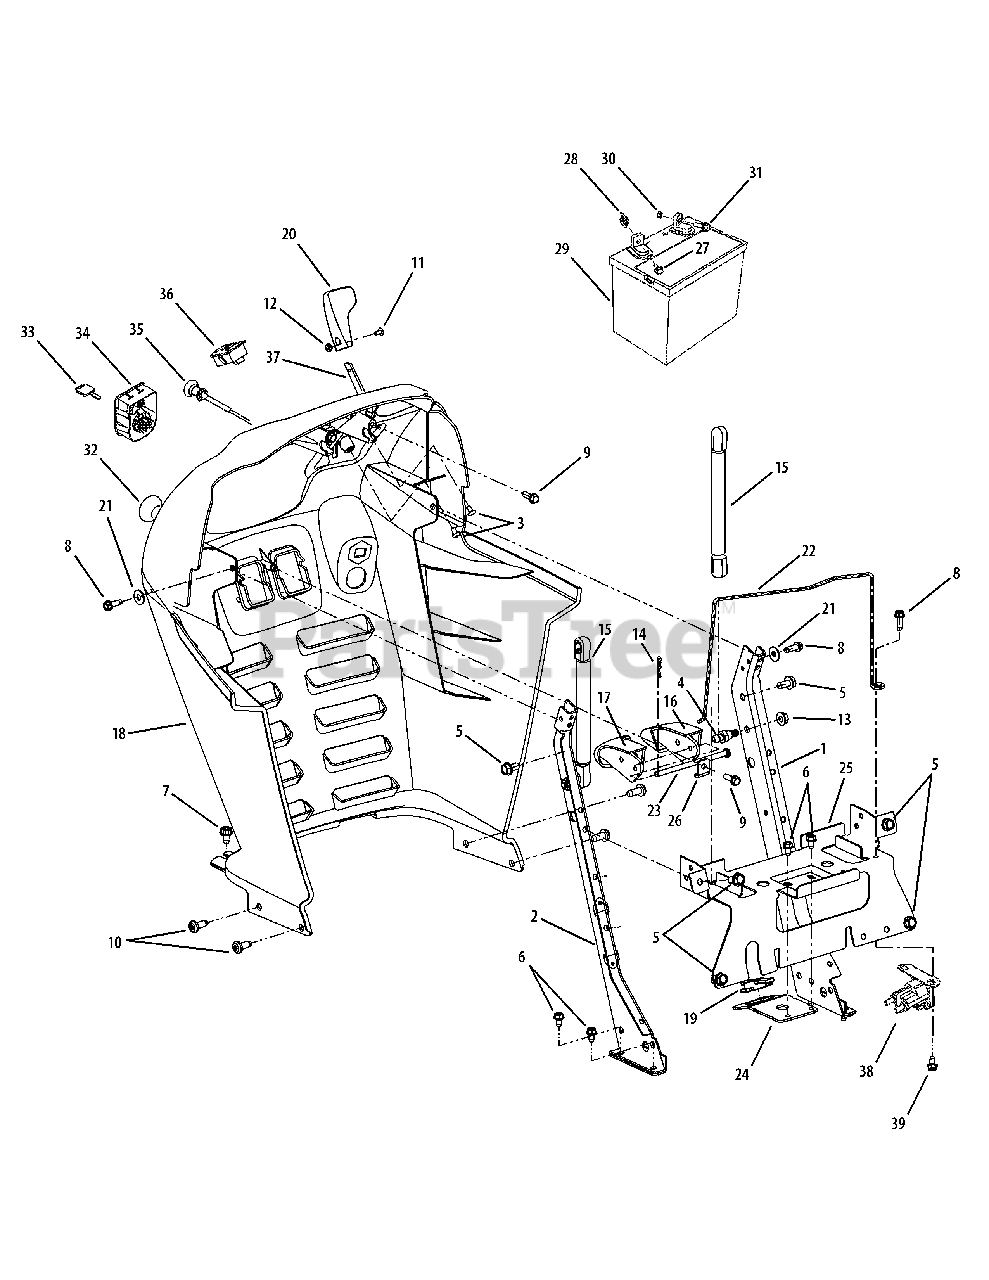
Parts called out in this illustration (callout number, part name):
4	Screw, Shoulder Ball, 5/16-18 x .48
5	Screw, Hex, 5/16-18 x .750
6	Screw, Self-tapping, 1/4-20, 0.500
7	Screw, Hex, 5/16-18 x .500
8	Screw, 1/4-20, .750
9	Screw, 1/4-15, 0.750
10	Screw, Torx Hd. Tapp. 5/16-18 x .75
11	Screw, Machine, #8-32, 0.375
12	Nut, 8-32
13	Nut, Flangelock, 5/16-18
14	Internal Cotter Pin, .072 x 1.13
15	Gas Spring Cylinder
16	Lever, Dash, Brake
17	Lever, Dash, Cruise
18	Cub 1500 Dash
19	Steering Column Bearing
20	Knob, Throttle Control
21	Washer, Flat, .28 x .74 x .063
23	Rod, .250 Dia x 4.25 Lg.
27	Shoulder Screw, .250 x .150, 1/4-20
28	Wing Nut, 1/4-20
29	Battery, 235 CCA
30	Nut, Sems, 1/4-20
31	Screw, Flange, 1/4-20, .75,
32	Switch, PTO, Yellow
33	Ignition Key, Plastic
33	Ignition Key, Metal
34	Switch Module, Ignition
35	Choke, 40.5 x 2.0
36	Monitor, Sys. Indicator / Hour Meter
37	Throttle, 38.0 x 1.62
38	Solenoid, 12V, 100 Amp
39	Screw, 1/4-20
